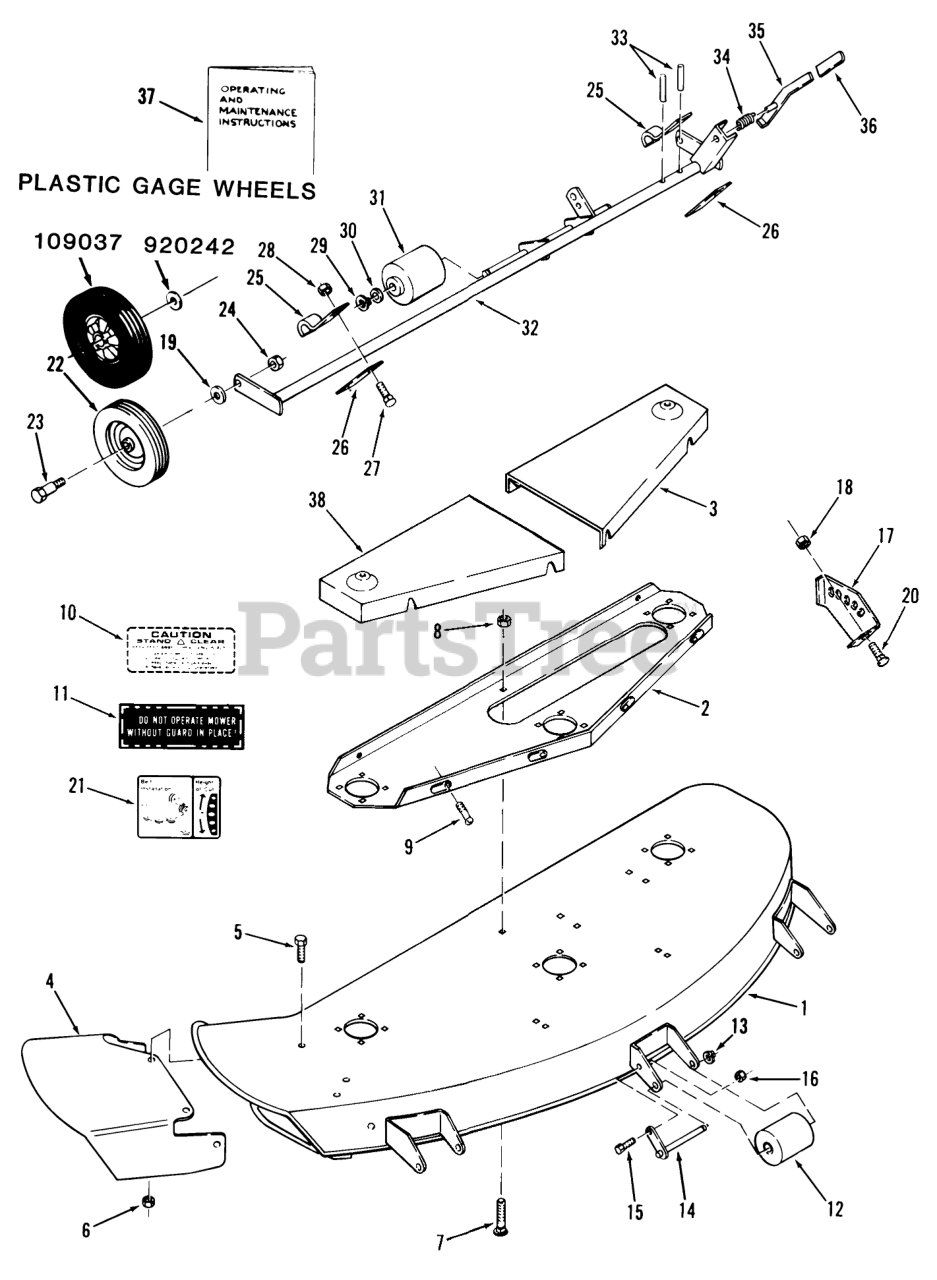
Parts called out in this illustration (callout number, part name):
1	ASSY-48 MOWER DEC R
2	Channel
3	Belt Cover LH
4	Chute Extension
5	Bolt
6	Nut
7	Bolt-Carriage
8	NUT
9	Screw
10	Caution Decal
11	Decal-Caution
12	Roller
13	Retaining Ring
14	Roller Shaft
15	H H C S
16	Nut
17	LH QUADRANT R
18	NUT
19	WASHER
20	Bolt
21	Decal, Height Adj. & Belt Diagram
22	Wheel 6 x 1.75 (w/5306 Bushings)
23	BOLT-SHOULDER
24	Nut
25	Machine Bolt
26	Bar
27	Bolt
28	NUT
29	Retaining Ring
30	Washer
31	Roller
32	ASSY-GAGE WHEEL S R
33	PIN-SPIROL
34	SPRING-COMPRESSION
35	Lever
37	Operating and Maintenance Instructions
38	Belt Cover RH
